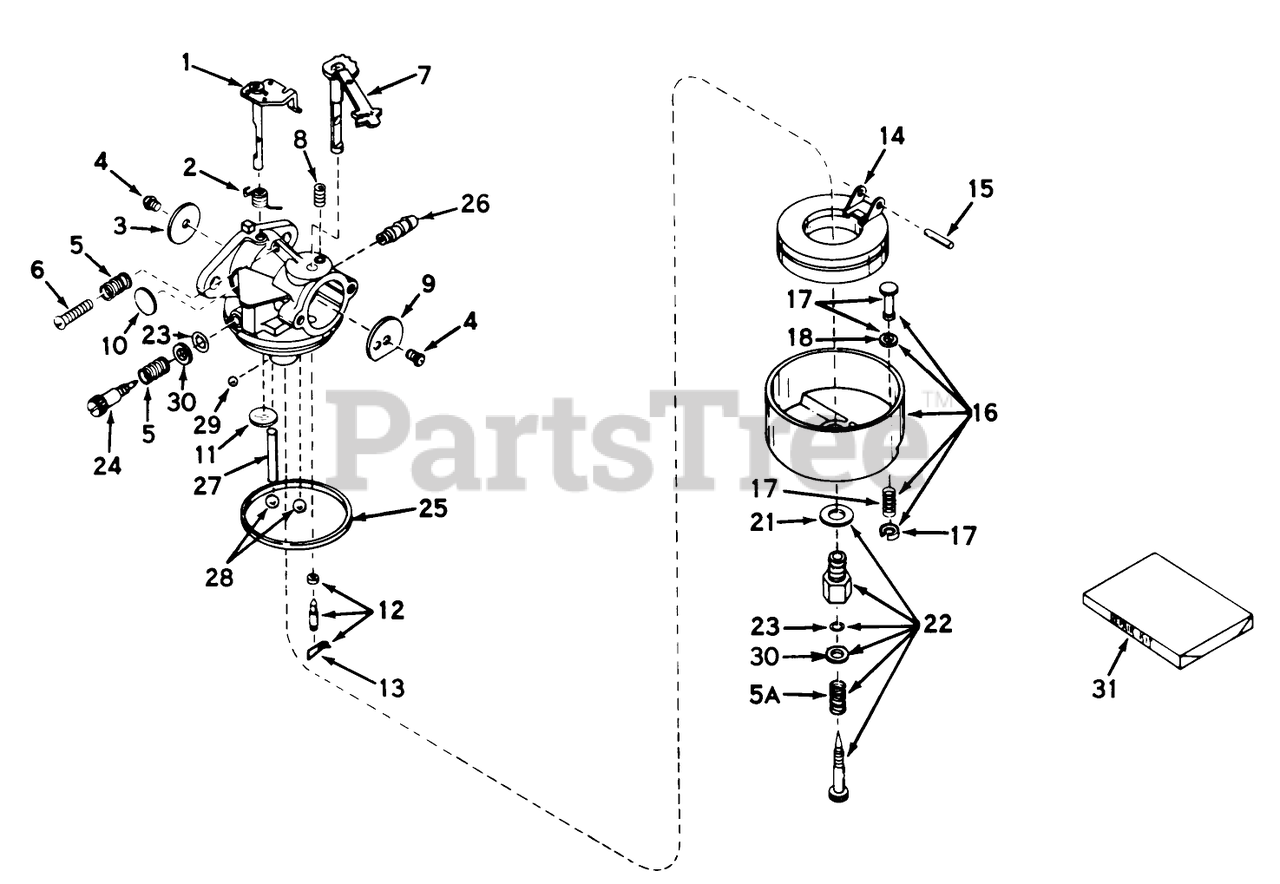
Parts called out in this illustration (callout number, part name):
1	Shaft/Lever-Throttle
2	Spring, Return
3	Shutter-Throttle
4	Screw-Shutter
5	Spring-Tension
5A	Spring
6	Screw-Throttle Crack Screw / Idle Speed
7	Shaft Lever Ass-y Choke
8	Spring-Positioning, Choke
10	Plug-Welch, Idle Mixture Well
11	Plug-Welch, Atmospheric Vent
12	Inlet Needle, Seat Clip Assy. (Incl. No. 13)
13	Clip-Spring
14	Float,Carburetor
15	Shaft-Float
16	Bowl Drain Assy., Float (Incl. No. 17)
17	Bowl Drain ASM
18	Gasket-Plunger, Drain
21	Washer-Bowl Nut
22	Adjustment Screw Assy., Main (Incl. Nos. 5A, 21 23)
23	ORing
24	Screw, Idle Adj.
25	O Ring-Bowl, Float
26	Fitting, Fuel inlet
28	Plug, Cup
29	BalI, Steel
30	Washer
31	Repair Kit (Incl. items marked *)
